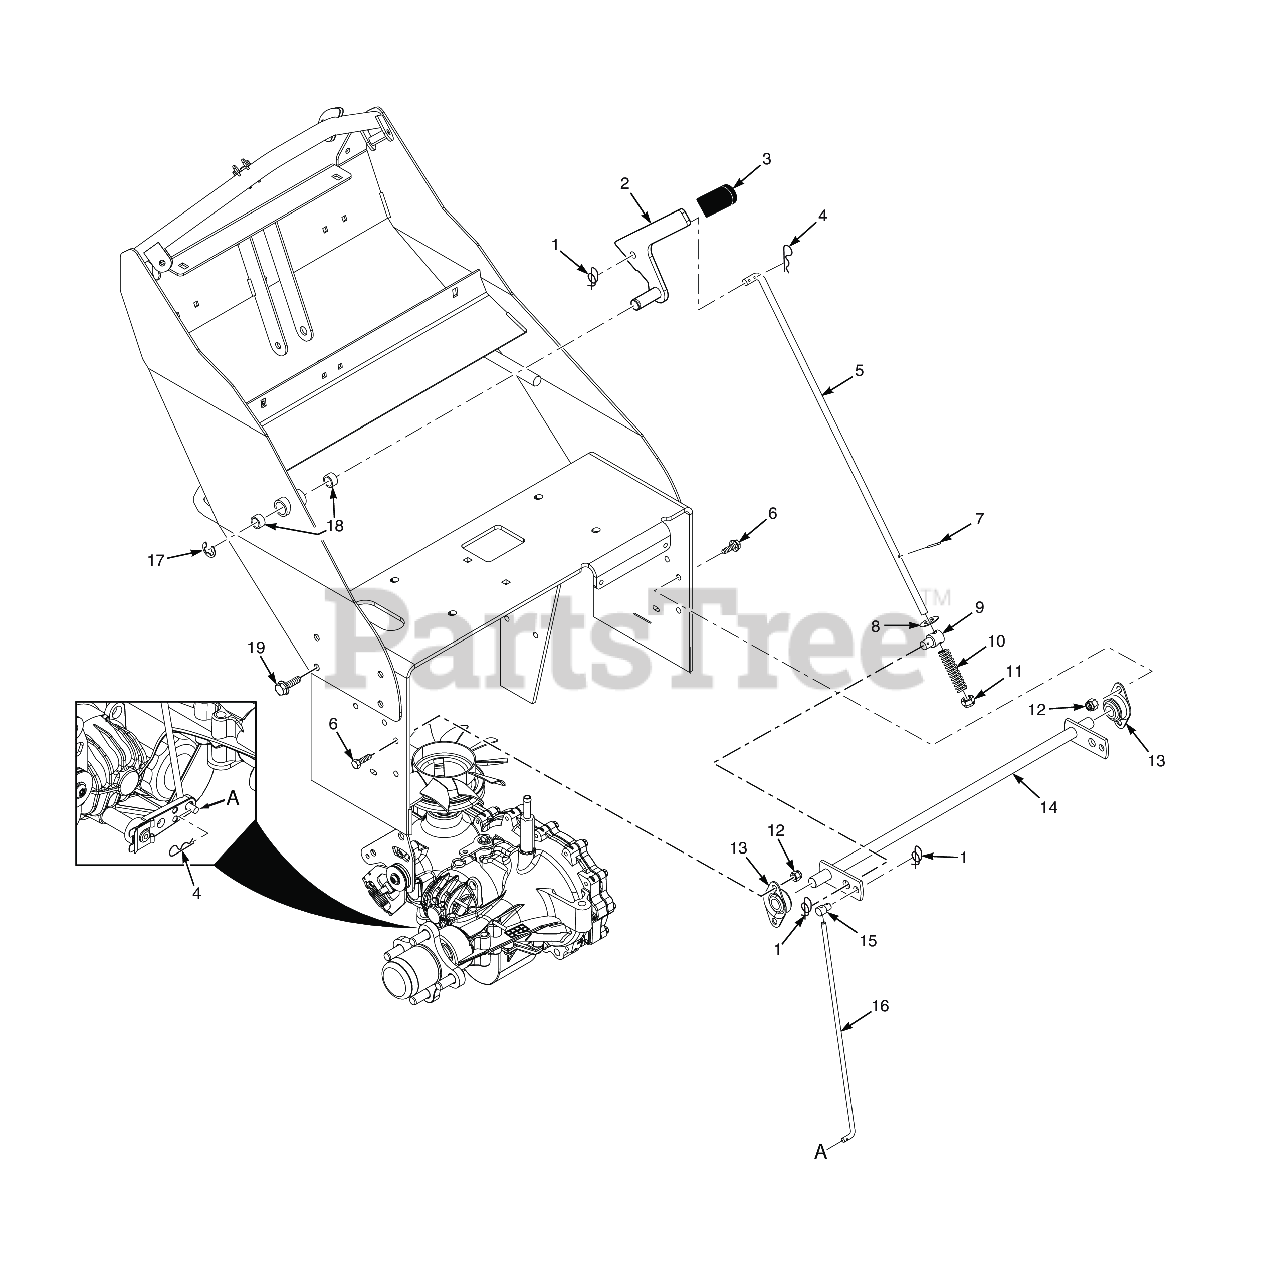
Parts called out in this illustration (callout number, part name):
1	Pin, Rue Cotter 3/8" Diameter
2	Brake Lever w/Grip
3	Grip, Parking Brake
4	HAIR PIN, .08 DIAMETER X 1-3/16"
5	Rod, Brake Linkage
6	Capscrew, 5/16-18 x .75 Serrated Flange Hex Head
7	Pin, Cotter 3/32 x .75"
8	Flatwasher, 3/8 (.406 x .812 x .065)
9	BUSHING, PIVOT SLIDE
10	Spring, Brake
11	Nut, Elastic Stop 3/8-16, grade 8 black
12	HEX NUT, ELASTIC STOP LOCK, 5/16-18
13	Bearing, Self Aligning - 5/8 I.D.
14	Weldment, Brake Bellcrank
15	Joint, Swivel
16	Rod, Brake Adjustment
17	RETAINING RING, 5/8" EXTERNAL "E"
18	Bearing
19	Capscrew, 3/8-16 x 1.0" Serrated Flange Hex Hd
